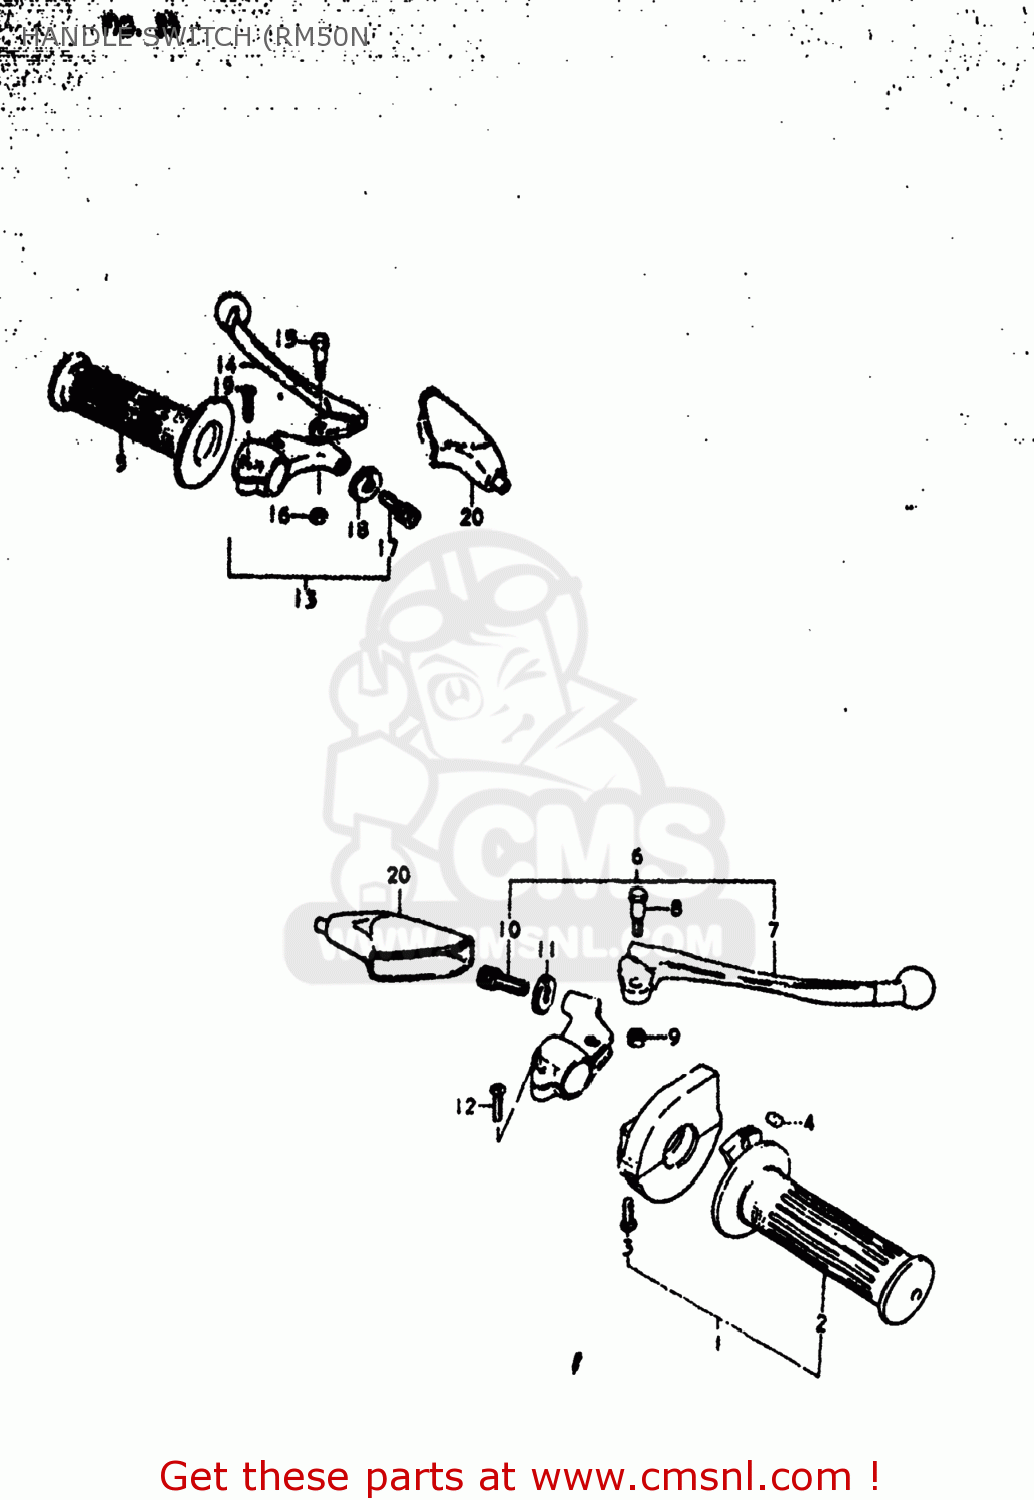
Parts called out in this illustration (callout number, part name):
1	CASE ASSEMBLY,THROTTLE
2	GRIP,THROTTLE
3	SCREW
4	PIECE,THROTTLE END
5	GRIP,L
6	LEVER ASSEMBLY,BRAKE
7	LEVER,BRAKE
8	BOLT,LEVER
9	NUT 6MM
10	ADJUSTER,CABLE
11	NUT,CABLE ADJUSTER
12	SCREW
13	LEVER ASSY,CLUTCH
14	LEVER,CLUTCH
15	BOLT,LEVER
16	NUT 6MM
17	ADJUSTER,CABLE
18	NUT,CABLE ADJUSTER
19	SCREW
20	COVER,CLUTCH LEVER
